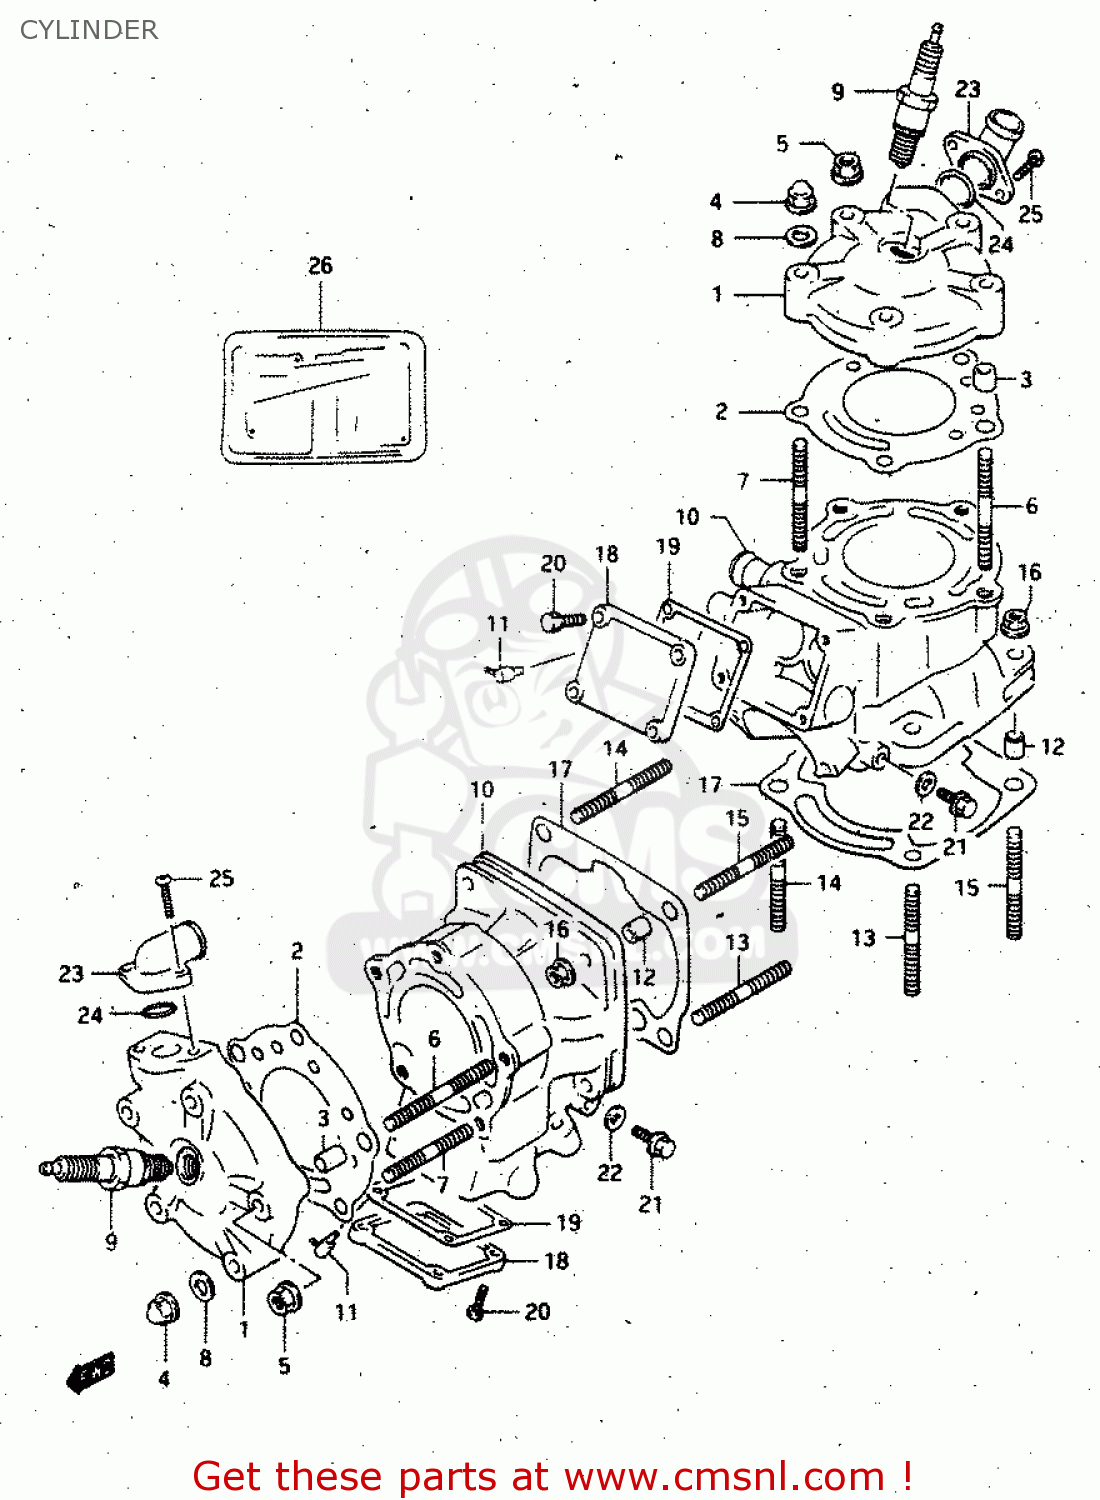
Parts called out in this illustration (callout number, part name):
1	HEAD,CYLINDER
2	GASKET,CYLINDER HEAD (NAS)
3	PIN
4	NUT
5	NUT
6	BOLT,HEAD STUD
7	BOLT,STUD
8	GASKET(8.5X17X2.3) (NAS)
9	PLUG,SPARK(BR9ECM)
10	CYLINDER
11	VALVE,OIL HOSE CHECK
12	PIN
13	BOLT,STUD
14	BOLT,STUD
15	BOLT,STUD
16	NUT
17	GASKET,CYLINDER (NAS)
18	COVER,CYLINDER NO.2
19	GASKET,CYL COVER NO.2 (NAS)
20	BOLT
21	BOLT
22	GASKET(6.2X13X1.2) (NAS)
23	CONNECTOR,WATER HOSE
24	O RING(D:1.9,ID:19.8)
25	SCREW
26	GASKET SET (NAS)
